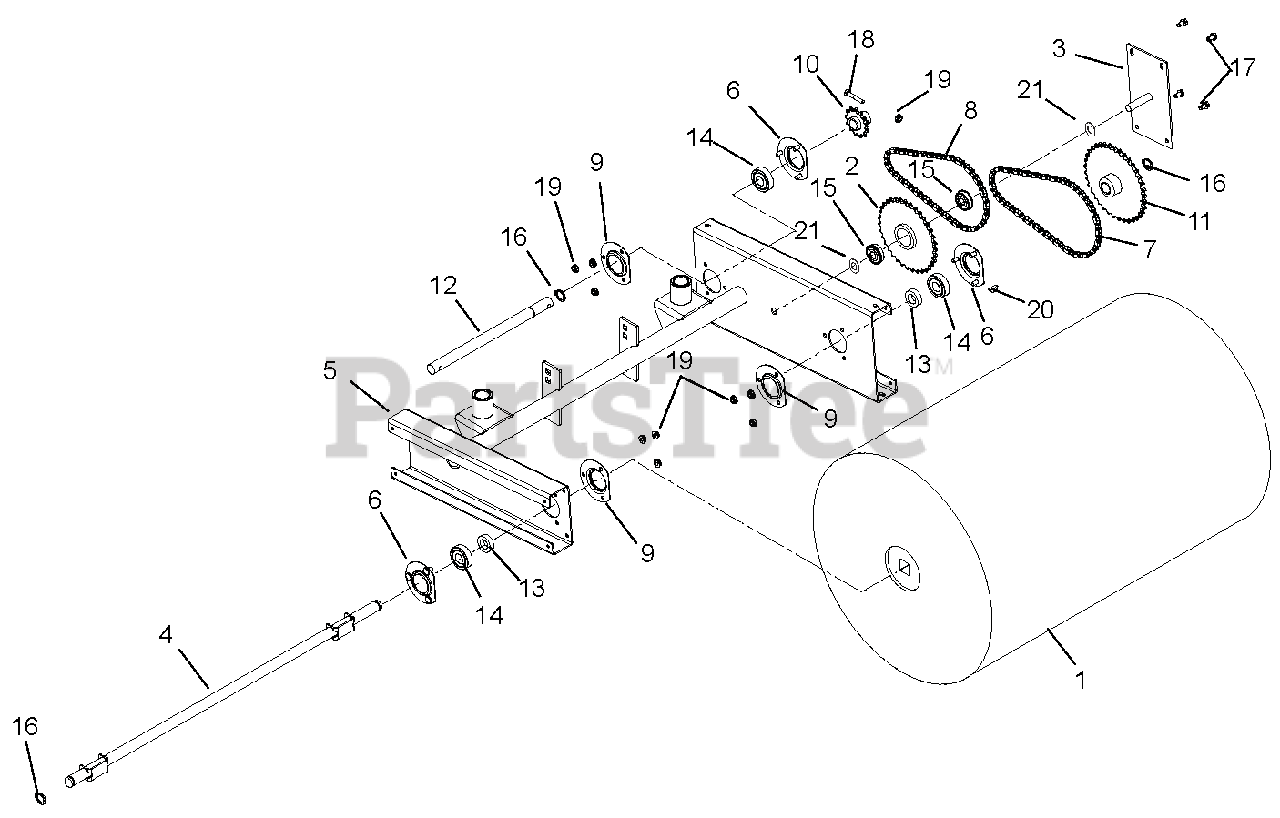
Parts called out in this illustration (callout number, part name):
1	BRUSH, 18"DIA X 28"WIDE
2	SPROCKET, REDUCTION IDLER
3	PLATE, IDLER REDUCTION MOUNT
4	SHAFT, 28" BRUSH
5	FRAME, POWER BROOM-DELUXE
6	BEARING FLANGE
7	CHAIN, #40-54 LINKS
8	CHAIN, #41-50 LINKS
9	BEARING FLANGE
10	SPROCKET, DRIVE
11	SPROCKET, DRIVEN
12	SHAFT, TRANSMISSION
13	SPACER .755X1.250X.370
14	BRG-BALL .750X1.750X.50
15	BRG-BALL .50X1.38X.438 SEALED
16	RG-RTNG-EXT .689X.078
17	SCR-TAP .25-20X.50 HWH TR YWZ
18	@BLT-HEX .25-20X1.75 GR5 YWZC
19	@NUT-LK-TOP-FLG .25-20 YWZC
20	KEY-WDRF .188X.75X.313 SAE 9
21	@WSHR-FL-STL.563X1.38X.109YWZC
